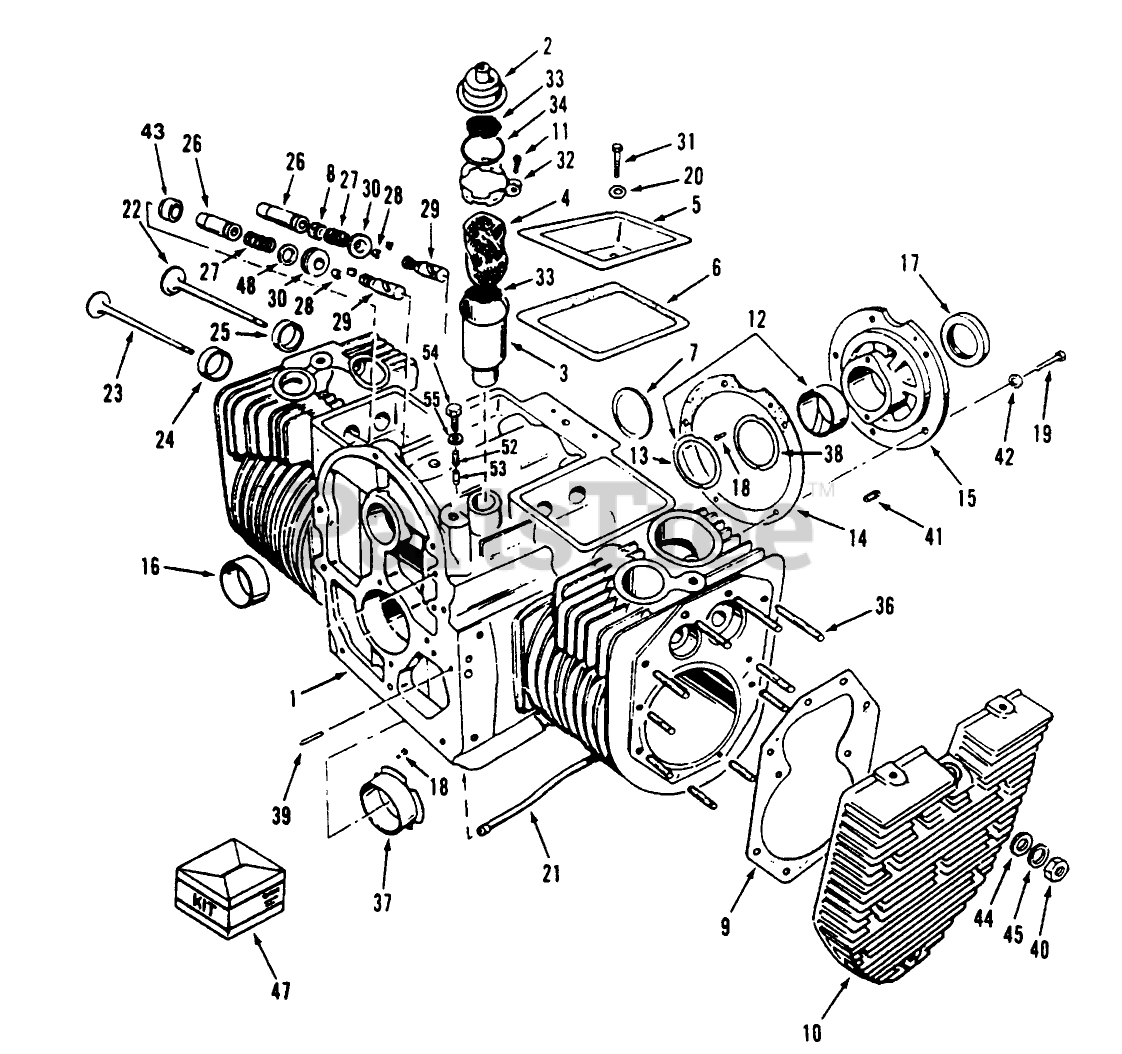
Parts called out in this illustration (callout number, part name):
1	Block-Short 24 HP Spec G (Incl. Ref. #3, 7, 13-16, 18, 21, 24-26, 30, 36, 38, & 39)
2	BREATHER-CAP AND VALVE
3	TUBE-BREATHER
4	FILTER
5	VALVE COMPARTMENT
6	GASKET-VALVE COVER
8	SEAL-INTAKE VALVE
9	GASKET-CYLINDER HEAD
10	HEAD-CYLINDER
11	SCREW-TAPPING, ROUND HEAD
12	BEARING KIT (STANDARD SLEEVE)
13	WASHER
14	GASKET
15	PLATE-BEARING, REAR
16	SLEEVE-BEARING
18	PIN-DRIVE
19	HEX HD CAPSCREW
20	WASHER
21	TUBE-OIL, CRANKCASE
22	Intake Valve
23	Exhaust Valve
24	INSERT
25	INSERT-VALVE SEAT
26	GUIDE-VALVE, EXHAUST
27	SPRING
28	LOCK-VALVE SPRING
29	TAPPET
30	ROTOCAP
31	SCREW - CAP HEX HEAD
32	Clamp
33	SCREEN-BREATHER TUBE
34	SEAL - O-RING
36	STUD-CYLINDER HEAD
37	KIT-BEARING, SLEEVE
39	PIN-GEAR COVER
40	NUT-HEX
41	SCREW-SET
42	WASHER-FLAT
43	Cap-Exhaust Valve
44	WASHER-FLAT HD, TREATED
45	WASHER-LOCK, COMPRESS
47	KIT-GASKET CARB REM
48	WASHER
